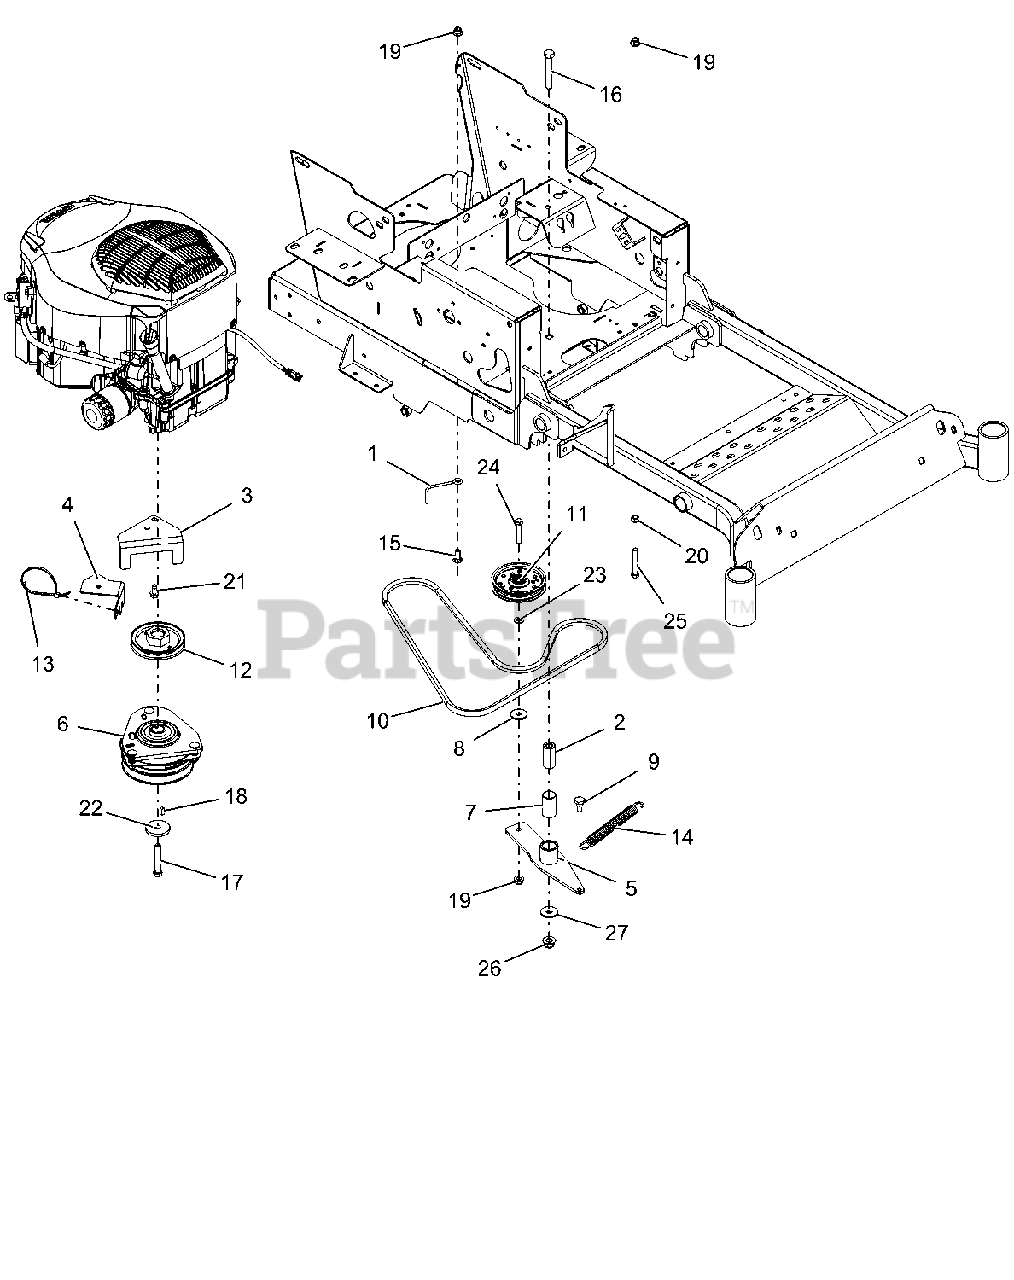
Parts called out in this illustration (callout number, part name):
1	BELT FINGER
2	BSHG, SPCR .502X.997X2.03 PM
3	ANCHOR - OGURA CLUTCH - HD
4	GUARD, HD CLUTCH WIRE
5	HYDRO DRIVE IDLER ARM WMT -BLK
6	CLUTCH, OGURA GT1A
7	BSHG, 1.00 X 1.125 X 1.937
8	WSHR-FL-STL .406X1.375X.135 YZ
9	BLT,SHLDR EP .38-16X.30 HEX YZ
10	V-BELT, 4L-WRAPPED
11	ASM, 4" IDLER (.75 WIDE)
12	PULLEY-4.50OD X 1.002 ENGINE
13	CABLE TIE LG 5-1/2
14	SPRING, EXTENSION
15	@BLT-RDHDSQNK .38-16X1.00 G5YZ
16	@BLT-HEX .50-13X3.25 GR5 YWZC
17	BLT-HEX .44-20X2.75 G5 YZ EP80
18	KEY-SQ .25X.625X.25 SAE 8630
19	@NUT-LK-NYL-FLG .38-16 YWZC
20	@NUT-HEX .38-16 YWZC
21	@SCR-TAP .38-16X.75 HWH TR YWZ
22	WSHR-FL-STL .469X2.00X.25 YWZC
23	@WSHR-FL-STL.406X.812X.065 YWZ
24	@BLT-HEX .38-16X2.00 GR5 YWZC
25	@BLT-HEX .38-16X2.50 GR5 YWZC
26	@NUT-LK-NYL-FLG .50-13 YWZC
27	WSHR-FL-STL.511X1.441X.125 YWZ
